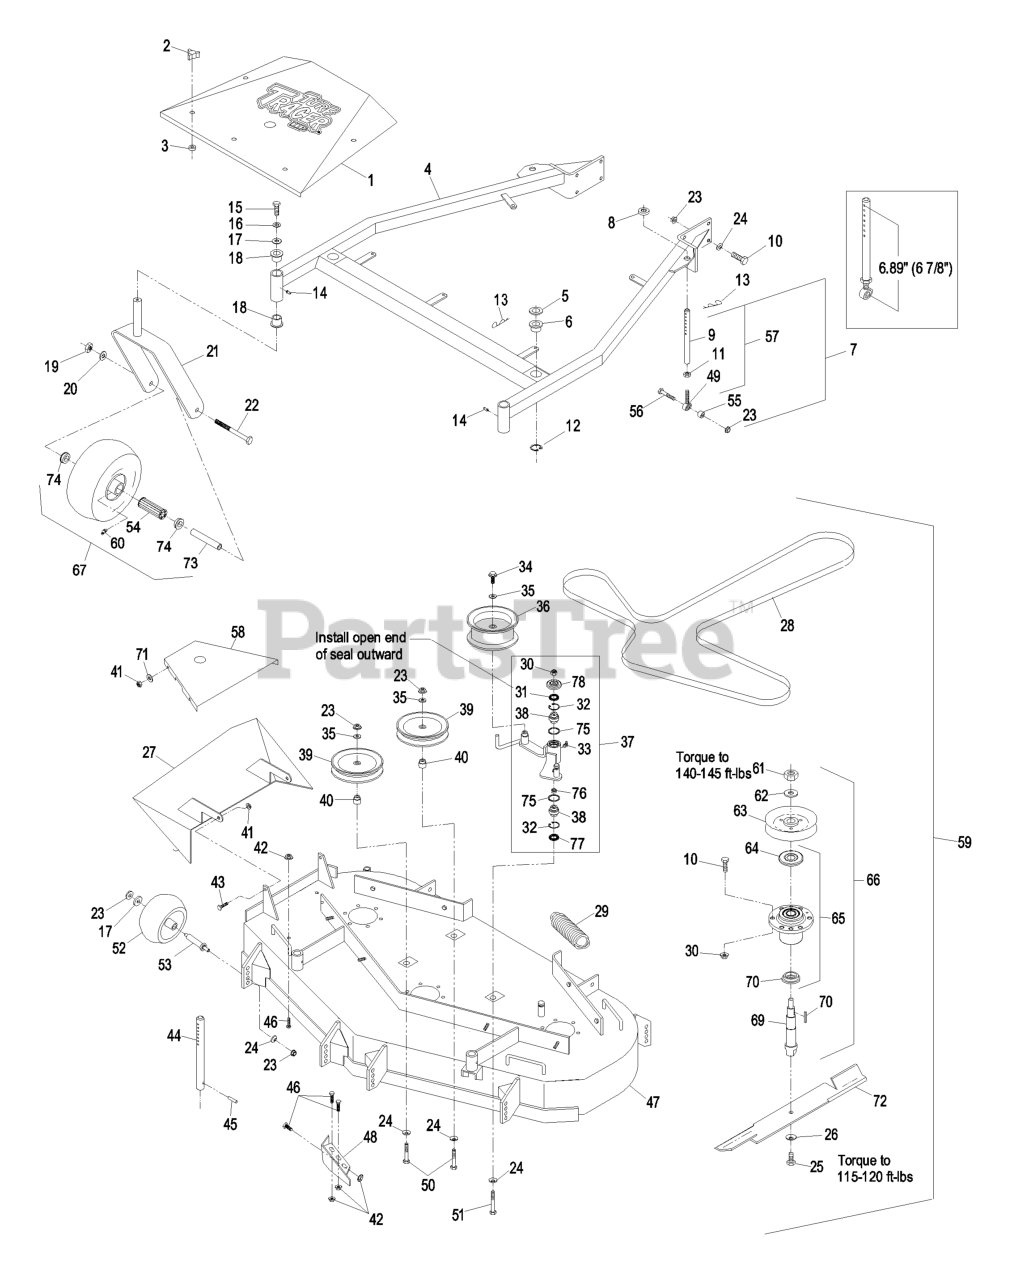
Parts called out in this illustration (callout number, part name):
2	KNOB-3 PRONG
4	SUPPORT,DECK W/BUSHINGS
5	SPACER-DECK SUPPORT
6	BUSHING-DECK
9	LINK,SUPPORT
10	SCREW-HH
11	NUT-HEX
12	RING-RETAINING
13	PIN,HAIR COTTER
14	FITTING-GREASE
15	SCREW-HH
16	WASHER-LOCK
18	BEARING-FLANGED
19	NUT-HH
20	WASHER-LOCK
22	SCREW-HH
23	NUT-HHF, WHIZ
24	WASHER-BELLEVILLE
25	SCREW-CAP
26	WASHER-SPRING
27	WLD,CHUTE DISCHARGE
28	BELT,DECK DRIVE
30	NUT-LOCK, NI
31	SEAL-LIP, SINGLE
32	RING-SNAP
33	FITTING-GREASE, 90 DEG
34	SCREW-HHF
35	WASHER-FLAT
37	KIT, DECK IDLER TTHP48&52
38	BEARING-SPHERICAL
39	PULLEY-IDLER
40	BUSHING-IDLER
41	NUT-LOCK, NI
43	SCREW-HH
44	ROD,DECK SUPPORT
46	SCREW-HH
47	ASM,DECK W/DECALS TTHP52
48	WLD,BAFFLE DISCHARGE
49	BALLJOINT
50	SCREW-HH
51	SCREW-HH
52	ROLLER-SCALP, ANTI
54	BEARING
56	SCREW-HH
58	SHIELD,SIDE BELT 52
59	Asm, Deck Complete
60	FITTING-GREASE
61	NUT-HH
63	SHEAVE,W/HUB 5.72
64	GUARD-BEARING, TOP
65	KIT, CUTTER HOUSING
66	ASM, CUTTER HSG
67	KIT, SP CASTER WHEEL REPL
68	SPACER-GUARD, BOTTOM
69	SPINDLE,SHAFT
70	KEY-RECTANGLE
71	WASHER-FLAT
74	BUSHING
77	SEAL-LIP, DOUBLE
78	GUARD-TOP
